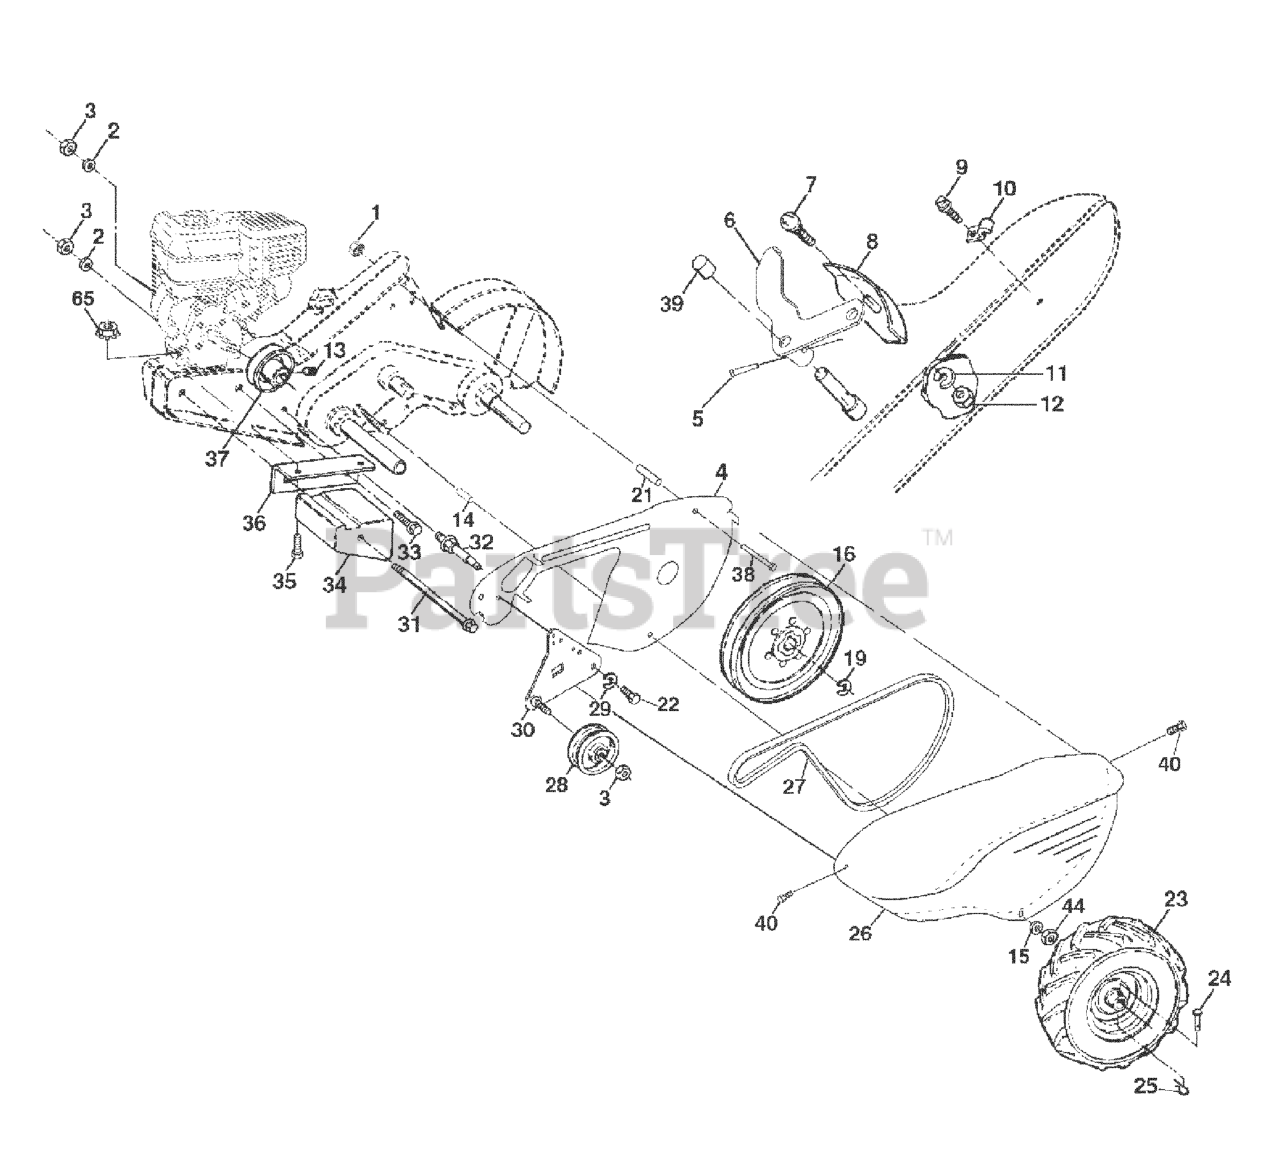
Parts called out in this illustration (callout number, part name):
1	NUT
2	WASHER, LOCK 3/8
3	NUT.HEX.3/8-16UNC
4	SHIELD
5	PIN.SPIROL.FLARED
6	LEVER ASM CRT
8	PANEL.INDICATOR.SHIFT.BLACK
9	TAPPING SCREW
10	CONDUIT.CLIP.PLATED
11	LOCKWASHER
12	NUT
14	SPACER CRT
15	WASHER
16	SHEAVE, TRANSMISSION
19	RETAINING RING LT
21	SPACER-SPLIT.327 X .42
23	TIRE.16X4-8.CHEVRON.TILLER
23	RIM
23	VALVE STEM LT
24	RIVET,DRILLED
25	RETAINER M
26	RP BELT GUARD
27	V-BELT
28	PULLEY-IDLER TI
30	BRACKET.ASM.IDLER.BLACK
31	BOLT.FIN.HEX.3/8-16UNC
32	SHIFT ARM CRT
33	BOLT
34	COUNTERWEIGHT.LH.CRT
35	Bolt, Hex 5/16-18 x 2
36	BRACKET LH CRT
37	RP.ENGINE PULLEY
38	BOLT
39	CAP.PLUNGER.BLACK
40	SCREW.HEX.WSH.SLT.#10-24X.50
44	NUT.71038.31-18.HEX.NYLOCK
65	LOCKNUT-FLANGE 5/16-18
